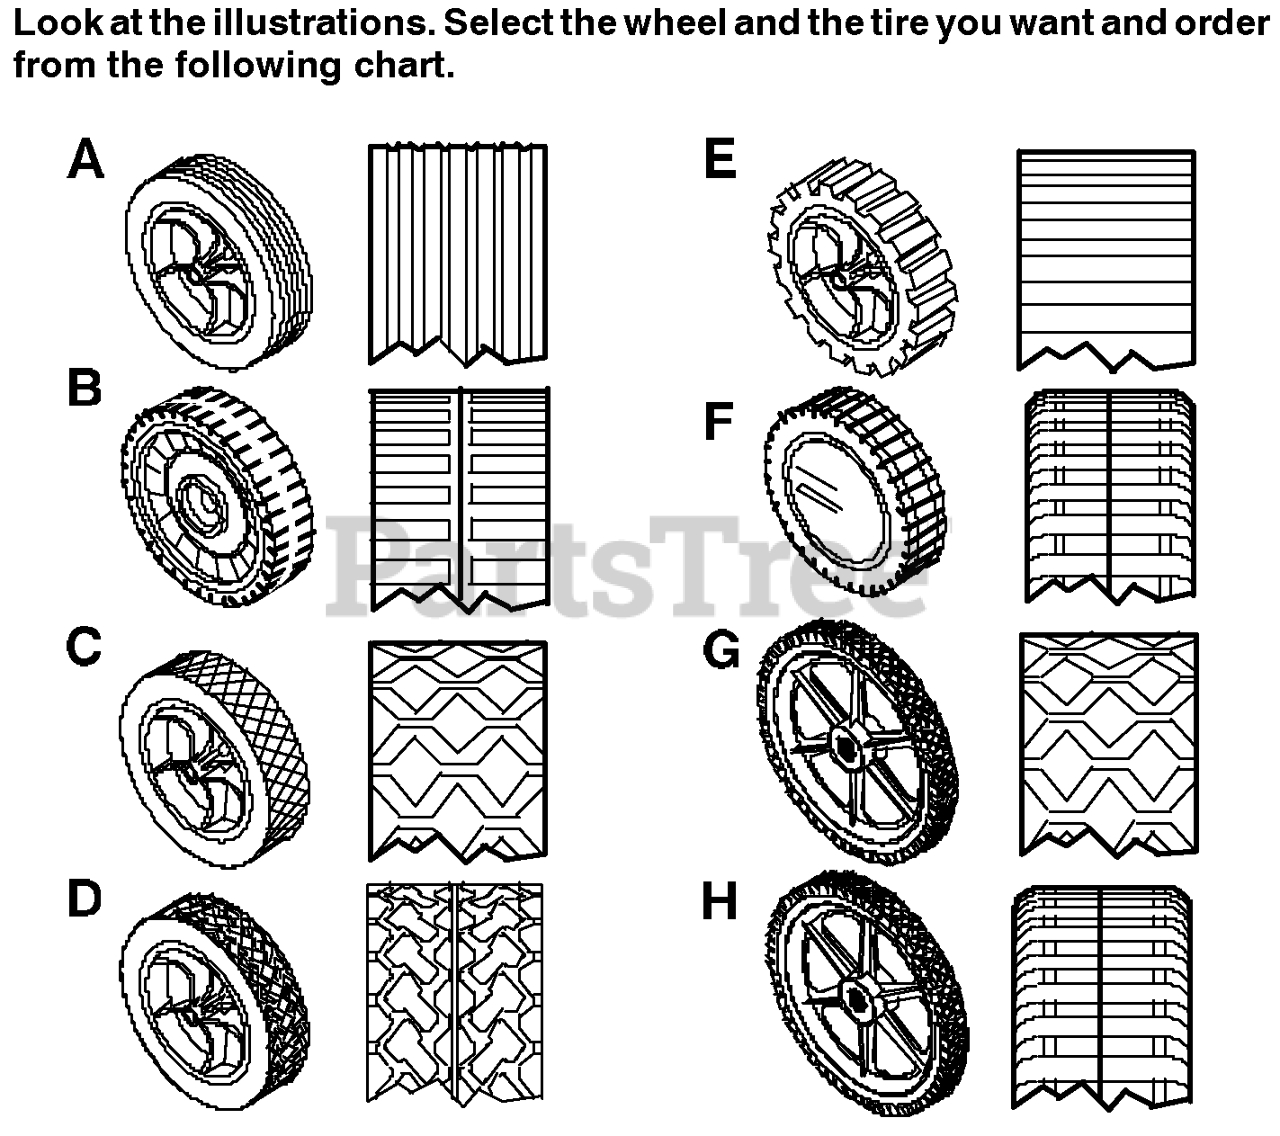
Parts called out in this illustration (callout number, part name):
A	WHEEL & TIRE ASSEMBLY, Light Gray, 8"
A	8-inch Plastic, Dark Gray
A	8-inch Metal, White
B	7-inch Plastic, White
B	7-inch Plastic, Light Gray
B	7-inch Plastic, Dark Gray
C	6-inch Plastic, White
C	7-inch Plastic, White
C	7-inch Plastic, Light Gray
C	7-inch Plastic, Dark Gray
C	8-inch Plastic, White
C	8-inch Plastic, Light Gray
C	8-inch Plastic, Dark Gray
C	8-inch Metal, White
D	7-inch Plastic, White
D	WHEEL & TIRE ASSEMBLY, White, 8"
D	8-inch Plastic, Light Gray
D	8-inch Plastic, Dark Gray
E	WHEEL & TIRE ASSEMBLY, White, 8"
E	8-inch Plastic, Dark Gray
E	8-inch Metal, White
F	WHEEL & TIRE ASSEMBLY, White, 8"
F	8-inch Plastic, Light Gray
F	8-inch Plastic, Dark Gray
F	8-inch Ball Bearing, Light Gray
F	8-inch Ball Bearing, Dark Gray
G	14-inch, White
G	14-inch, Light Gray
G	14-inch, Dark Gray
G	WHEEL & TIRE ASSEMBLY, White, 14"
G	14-in, Ball Bearing, Light Gray
G	14-in, Ball Bearing, Dark Gray
H	14-inch, White
H	14-inch, Light Gray
H	14-inch, Dark Gray
H	WHEEL & TIRE ASSEMBLY, Ball Bearing, 14"
H	14-in, Ball Bearing, Light Gray
H	14-in, Ball Bearing, Dark Gray
